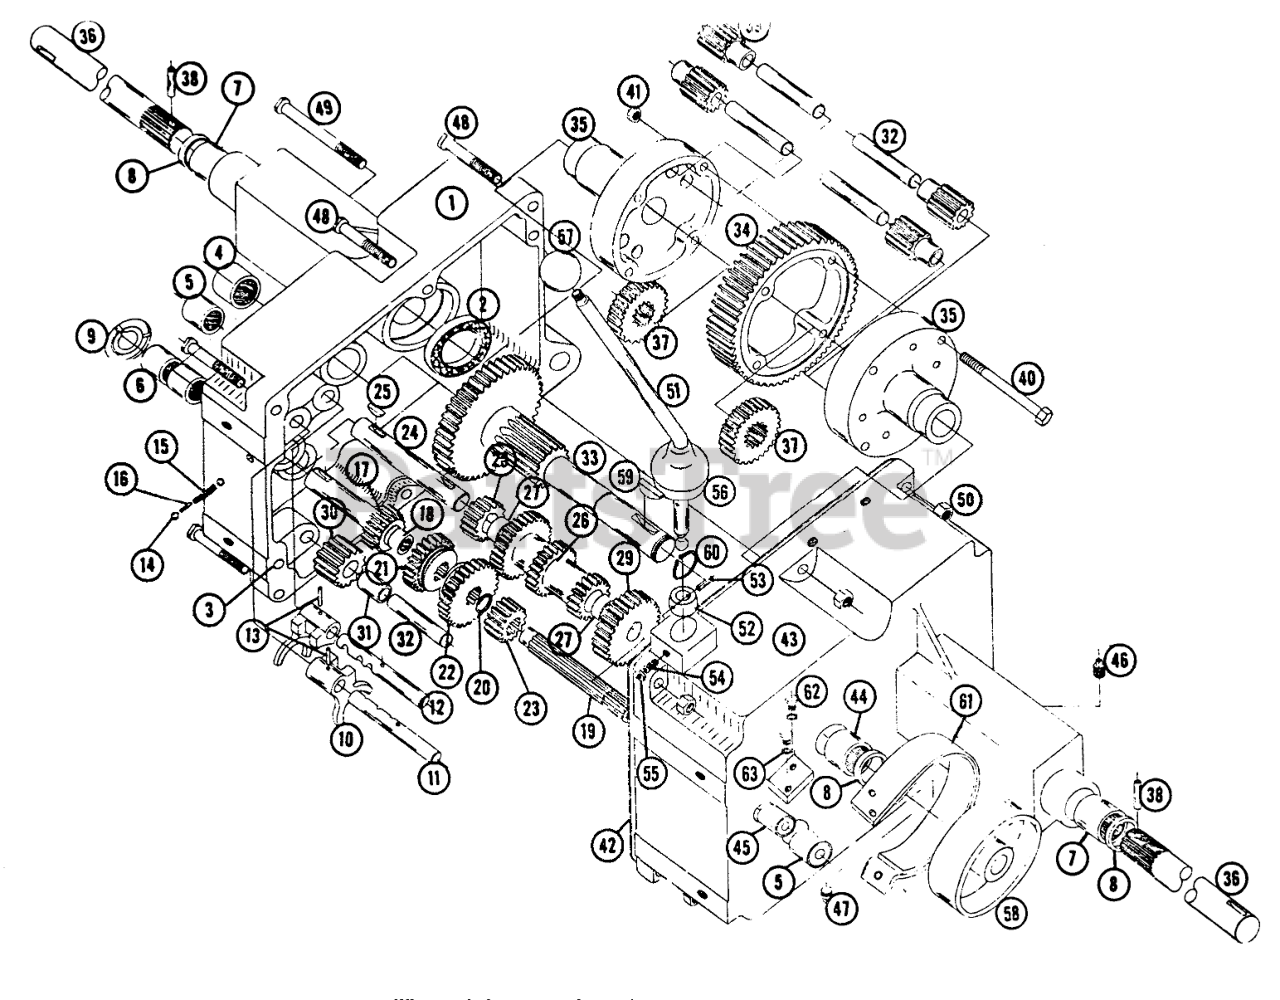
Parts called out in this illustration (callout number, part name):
3	PIN-DOWEL
4	BEARING-NEEDLE
5	BEARING-NEEDLE
7	BEARING-NEEDLE
10	FORK-SHIFT
13	PIN-ROLL
14	BALL-DETENT
18	BEARING-NEEDLE
20	Snap Ring 3/4 I.D.
23	GEAR
25	Key
27	BUSHING-BRONZE
29	GEAR-CLUSTER SHAFT
30	GEAR/BUSHING ASM-REVERSE IDLER
31	BUSHING
32	PIN-DIFFERENTIAL
34	SVC BULLT 394
35	DIFFERENTIAL CASE
37	AXLE GEAR
42	GASKET-TRANSMISSION
46	Plug 1/4 Pipe
47	Plug 3/8 Pipe
48	Bolt, 3/8 16 x 2
49	Bolt Hex 3/8-16 x 1
53	Roll Pin
54	SETSCREW
55	Nut 1/4-20
56	COVER-DUST
59	KEY-WOODRUFF
60	Snap Ring 1" Shaft
62	Bolt-1/4-20 x 5/8
63	Lockwasher
